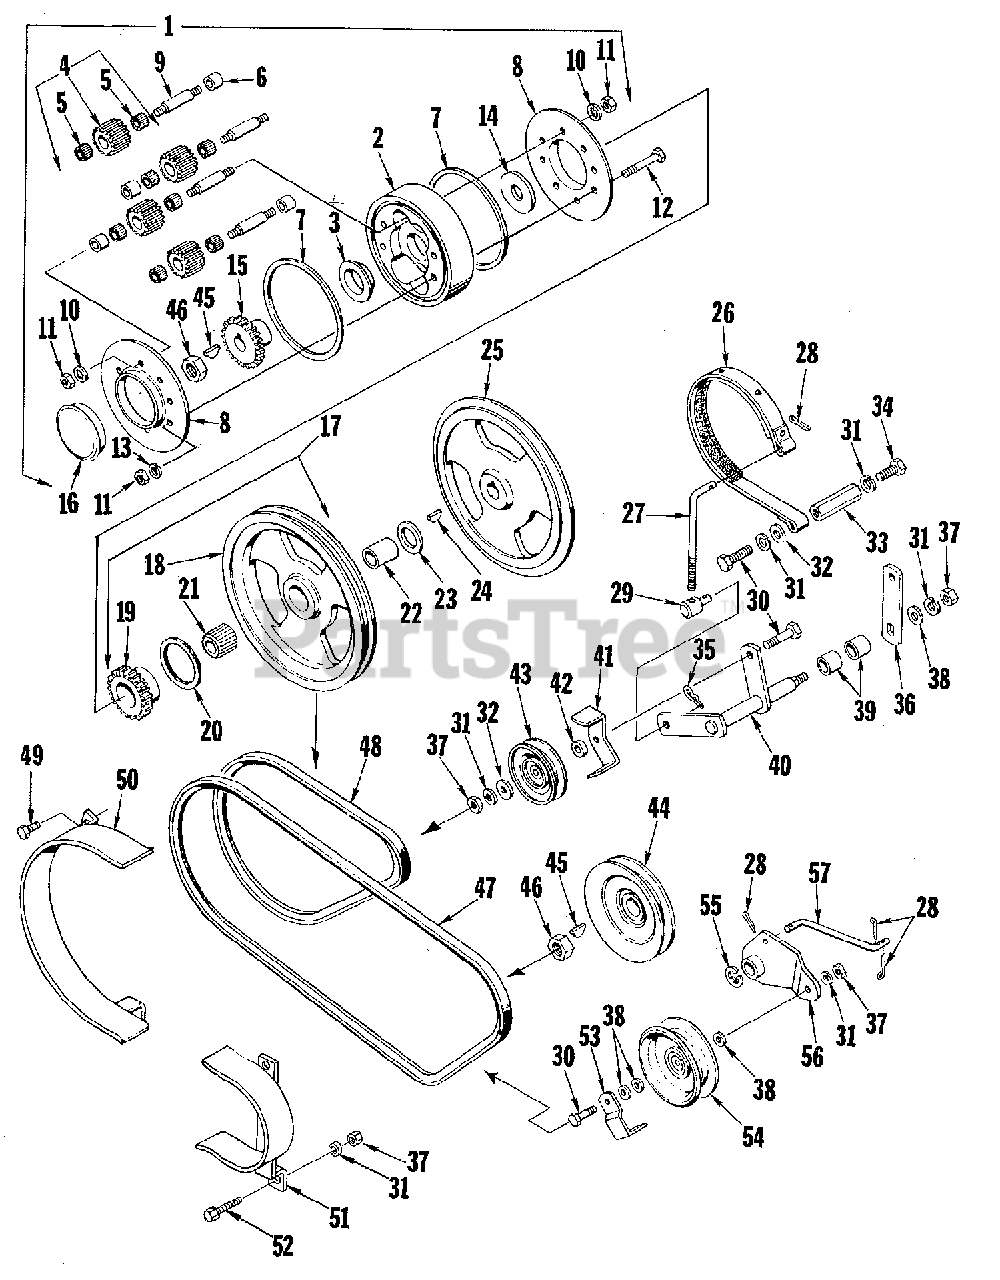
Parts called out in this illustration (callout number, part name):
1	PLANETARY ASSEMBLY
2	PLATETARY CARRIER
3	BEARING, Flanged
4	PINION, Differential Assembly
5	BEARING, Needle
6	BEARING, Sleeve
8	COVER, Differential
10	WASHER, Lock, Shakeproof, 5/16
11	NUT, Hex Full, 5/16 x 18
12	SCREW, Hex Cap, 5/16-18 x 2
13	WASHER, Lock, 5/16
14	WASHER, Thrust
15	GEAR, Differential
17	PULLEY ASSEMBLY
21	BEARING, Roller Seal
23	BEARING, Thrust
24	KEY, Woodruff, #9
25	PULLEY, Half
26	BRAKE BAND ASSEMBLY
30	SCREW, Hex Cap, 3/8-16 x 1-1/2
31	WASHER, Lock, 3/8
32	WASHER, Plain, 5/16
33	BRAKE, Anchor
34	SCREW, Hex Cap, 3/8-16 x 1
37	NUT, Hex Full, 3/8-16
38	WASHER, Plain, 3/8
40	LEVER ASSEMBLY
43	PULLEY, Idler
45	KEY, Hi-Pro, 3/16 x 3/4
46	NUT, Jam Lock, 3/4-16
49	SCREW, Taptite Hex Head, 5/16-18 x 1/2
50	GUARD ASSEMBLY PULLEY
51	GUARD ASSEMBLY, Belt
52	BOLT, Carriage, 3/8-16 x 1
54	PULLEY, Idler
56	LEVER ASSEMBLY IDLER
57	LINK, Clutch
